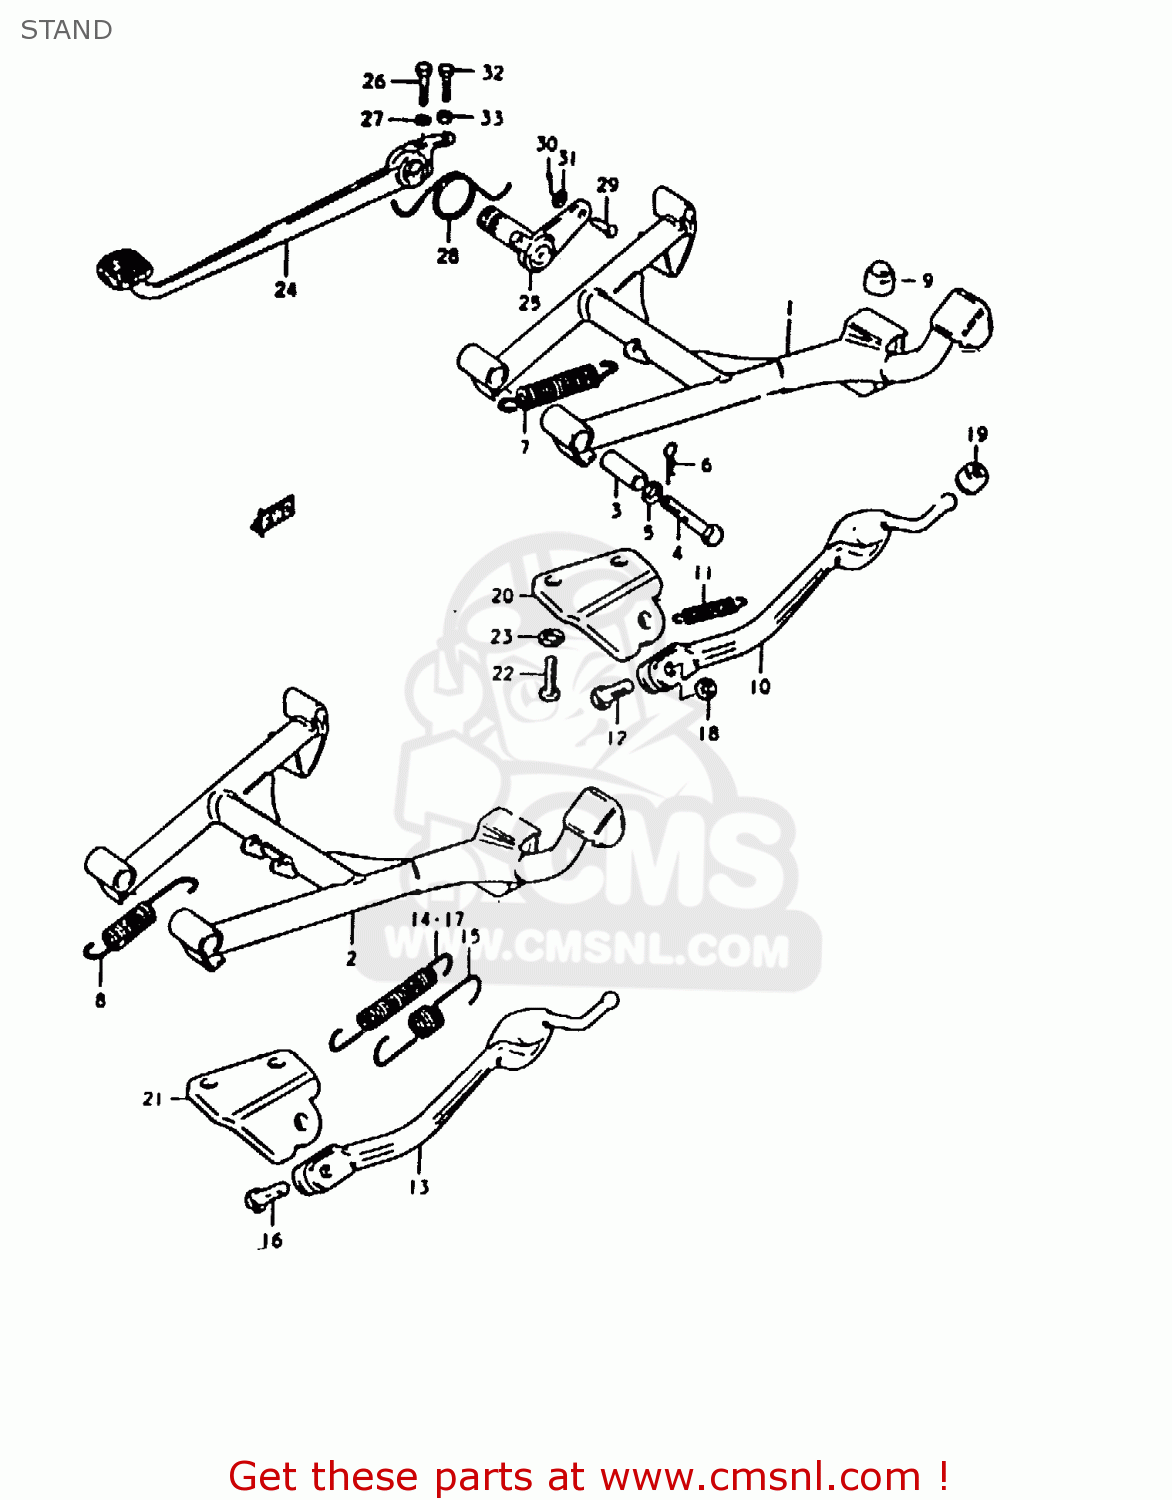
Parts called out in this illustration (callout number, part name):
1	STAND,CENTER
3	SPACER(10X16X38.8)
4	BOLT
5	LOCK WASHER
6	CLIP
7	SPRING
9	CUSHION
10	STAND,PROP
11	SPRING
12	BOLT(10X30)
18	NUT
19	CUSHION
20	BRACKET,SIDE STAND
22	BOLT
23	LOCK WASHER
24	PEDAL,BRAKE
25	ARM,BRAKE PEDAL
26	BOLT
27	LOCK WASHER
28	SPRING
29	PIN
30	PIN
31	WASHER
32	BOLT
33	NUT
